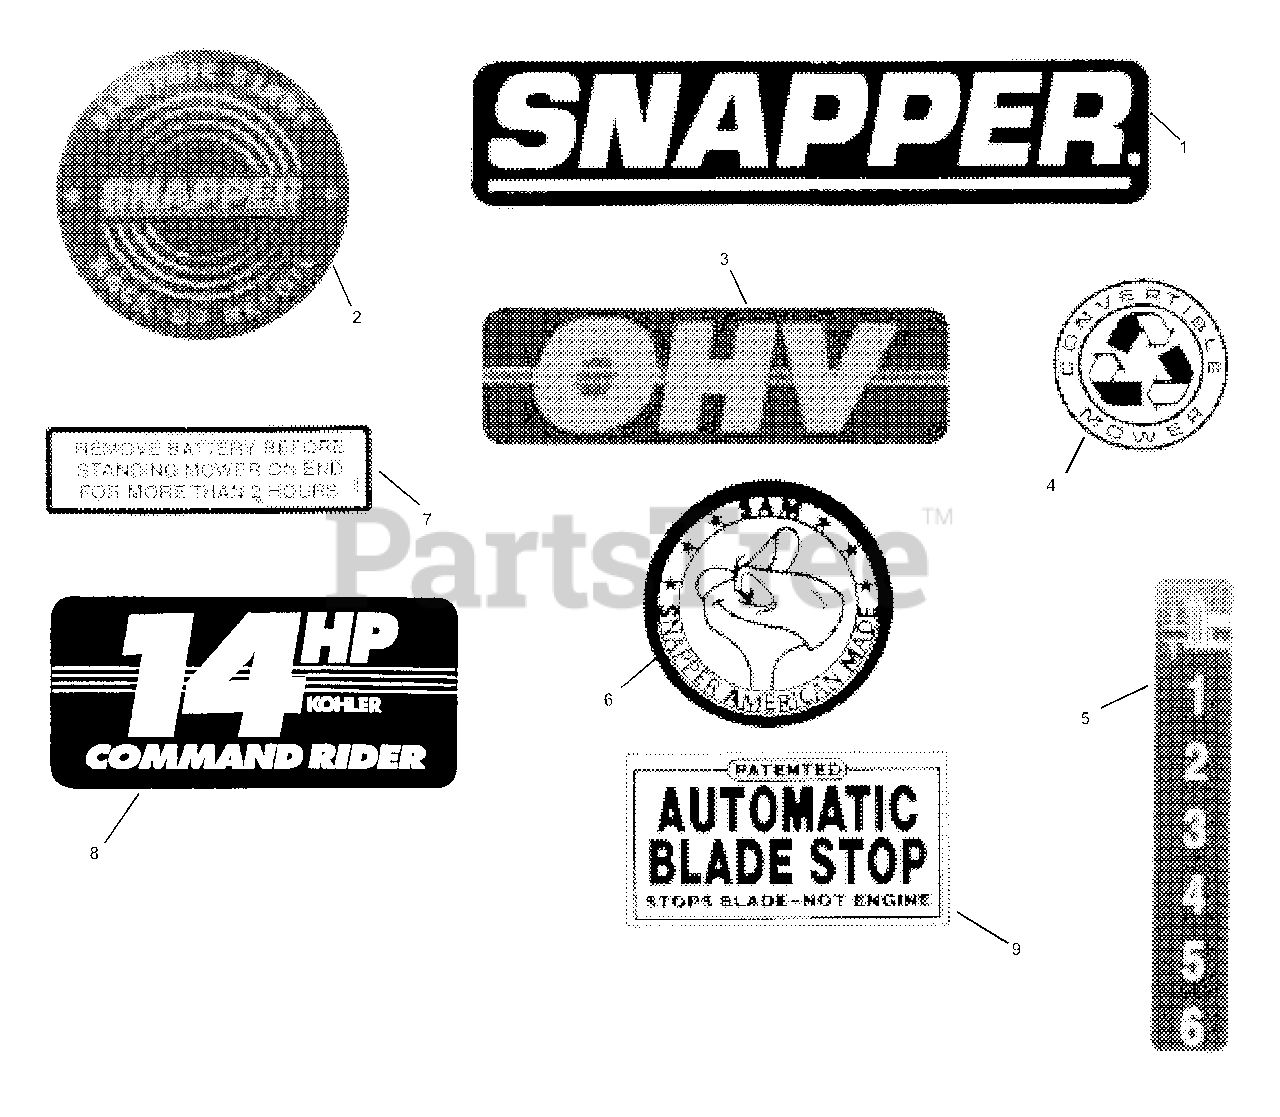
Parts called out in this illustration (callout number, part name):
1	DECAL, SNAPPER (Molded Logo)
2	DECAL, Back-Up Recoil (33" Kohler Engine Models)
3	DECAL, OHV (33" Kohler Engine Models)
4	LOGO, Convertible (Silver)
5	DECAL, Height Of Cut
6	MEDALLION, "Sam"
7	DECAL, Battery
8	DECAL, 14 HP (33" Kohler Engine Models)
9	DECAL, Automatic Blade Stop (Point Of Purchase Decal)
